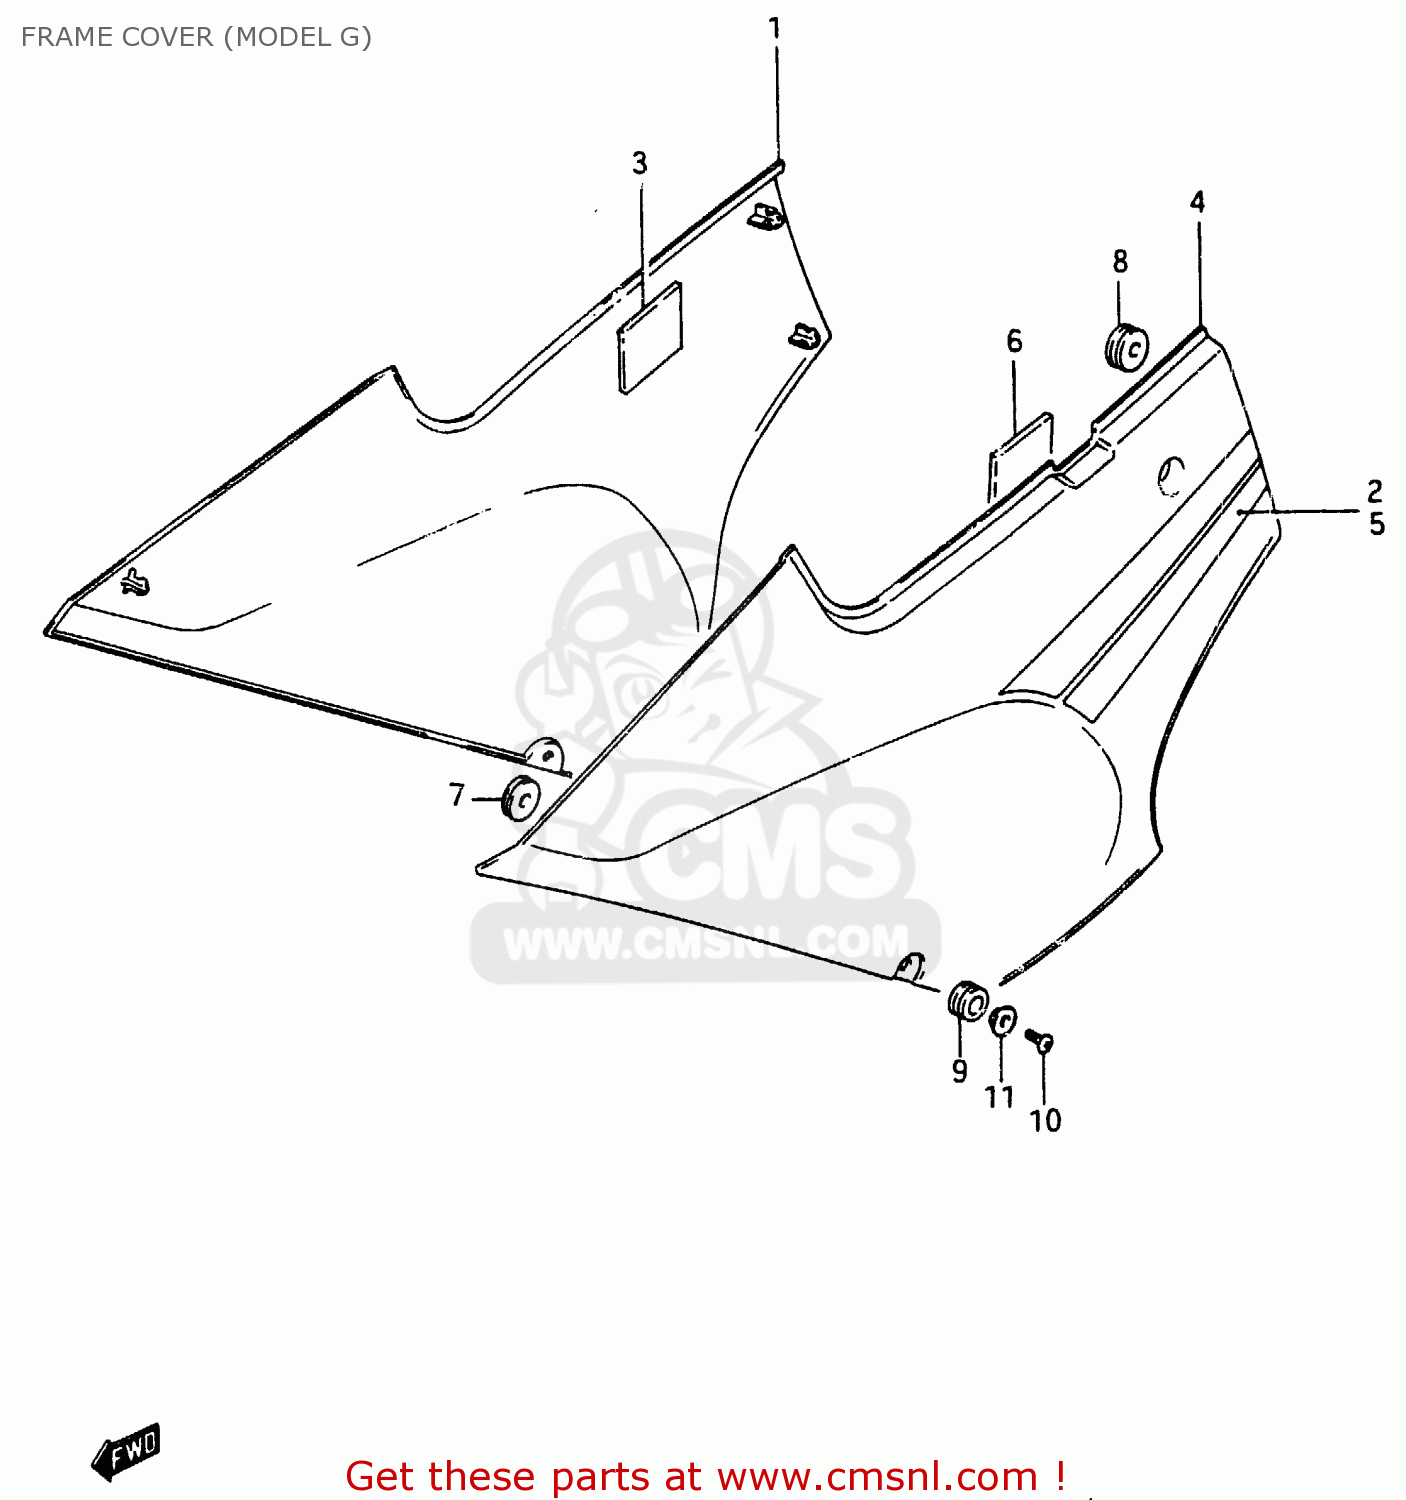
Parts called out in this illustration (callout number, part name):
1	COVER,FRAME,R
2	TAPE SET, FRAME COVER RH
3	PROTECTOR(170X95X3.0)
4	COVER,FRAME LH
5	TAPE SET, FRAME COVER LH
6	PROTECTOR,BATTERY
7	CUSHION
8	CUSHION
9	CUSHION,COVER HEAD
10	SCREW
11	WASHER
